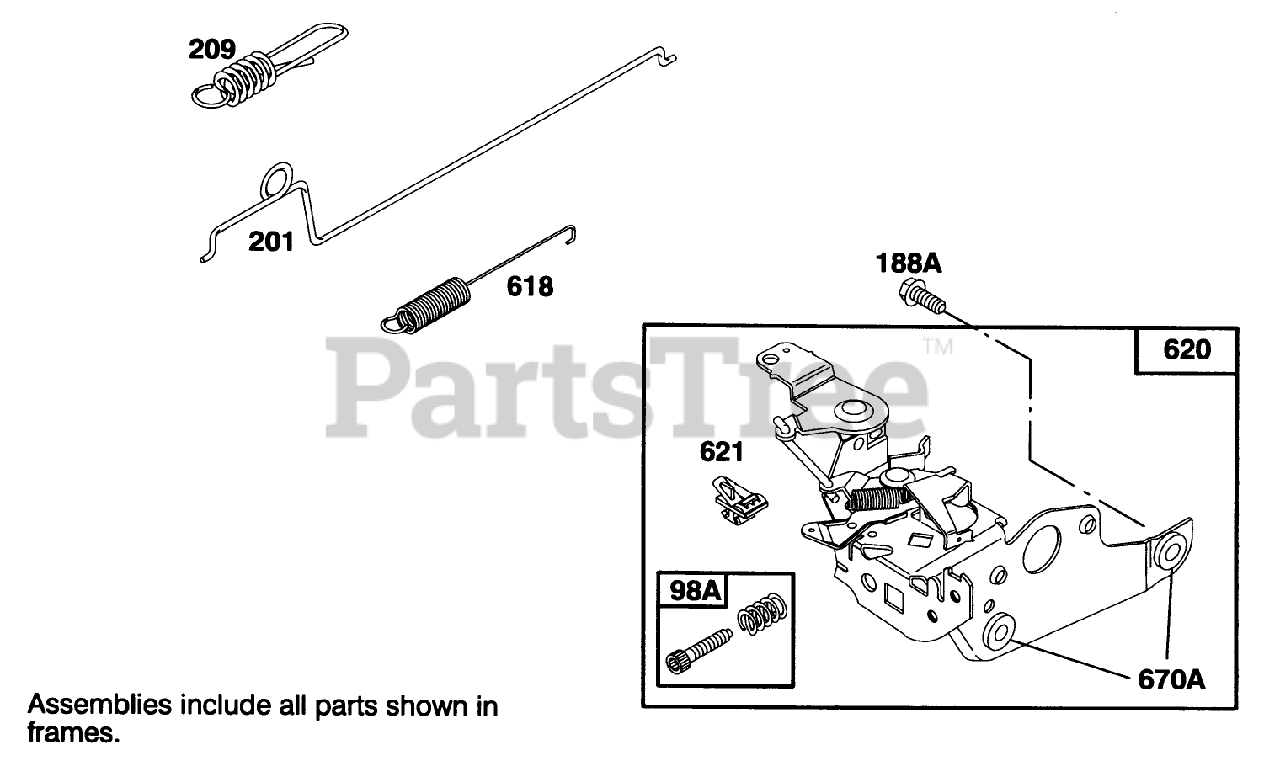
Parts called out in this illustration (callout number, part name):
98A	Screw Assy.
188A	Screw-Hex.
201	Link-Govemor
209	Spring-Govemor
618	Spring-Choke
620	Bracket-Control
621	Switch
670A	Spacer
